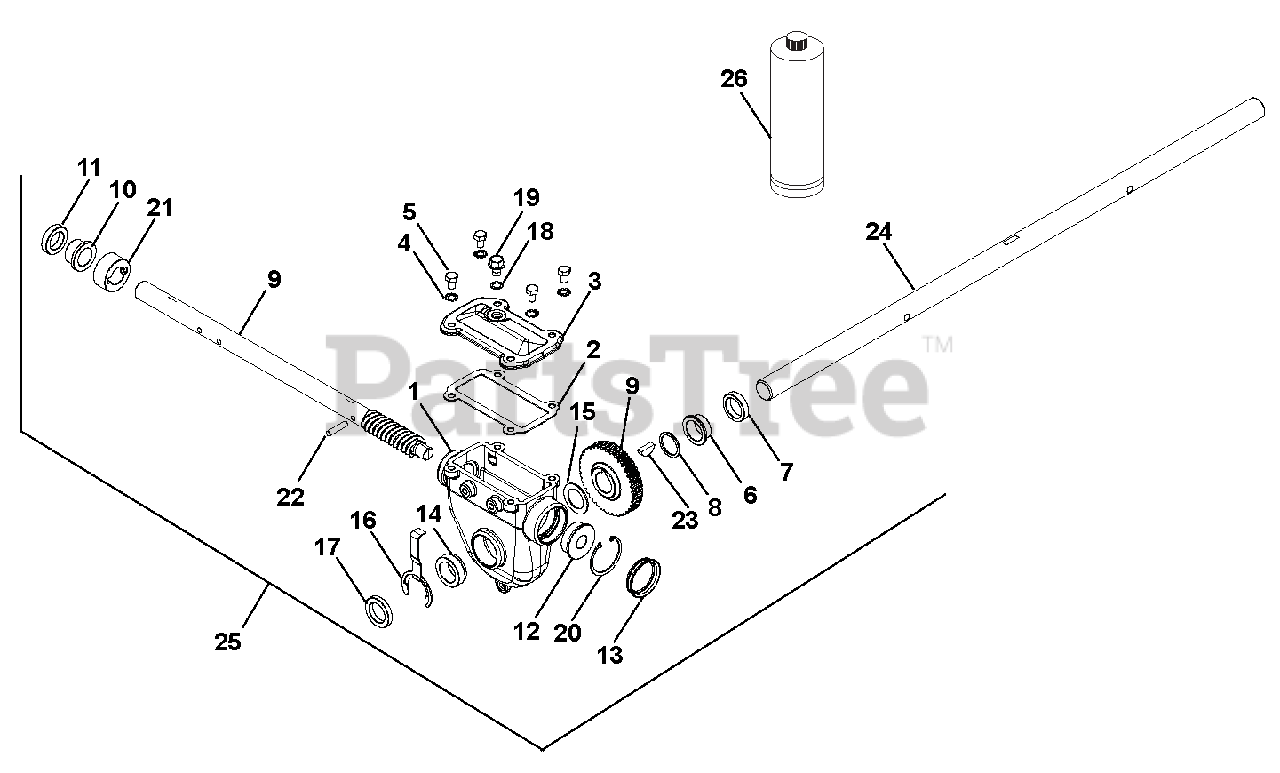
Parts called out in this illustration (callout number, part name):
1	GEARCASE, LARGE MACHINED
2	GASKET, TOP - LARGE GEARCASE
3	COVER, TOP - LARGE IRON
4	@WSHR-LK-EXT.326X.599X.031YWZC
5	@BLT-HEX .31-18X.50 GR5 YWZC
6	BSHG-FLG 1.006X1.128X.555X1.45
7	SEAL-OIL .999X1.375X.312 TB2-H
8	WSHR-FL-STL 1.010X1.505X.062YZ
9	ASSY, WORM SHAFT & GEAR
10	BSHG-FLG .879X1.128X.75X1.45
11	SEAL-OIL .873X1.375X.312 TB2-H
12	BSHG-FLG .628X1.503X.58X1.725
13	COVER, GEAR CASE 1.75"
14	BSHG-FLG LARGE, RIGHT
15	WSHR-FL-STL 1.010X1.250X.068YZ
16	BUSHING RETAINER, LARGE
17	SEAL-OIL .999X1.500X.250 TB2-H
18	WSHR-BND-SEAL .38X.75X.11 GALV
19	@SCR-ROLOK .38-16X.50 HWH YWZC
20	RG-RTNG-INT 1.750X.062
21	THRUST COLLAR, .875"ID SLIPFIT
22	PIN-STR .250X1.12 6150
23	KEY-WDRF .25X.875 HRD #A
24	SHAFT, RAKE-28"
25	GEAR CASE, 28" IRON PRO TOP-LD
26	ARIENS L3 LUBE, 8 OZ BOTTLE
